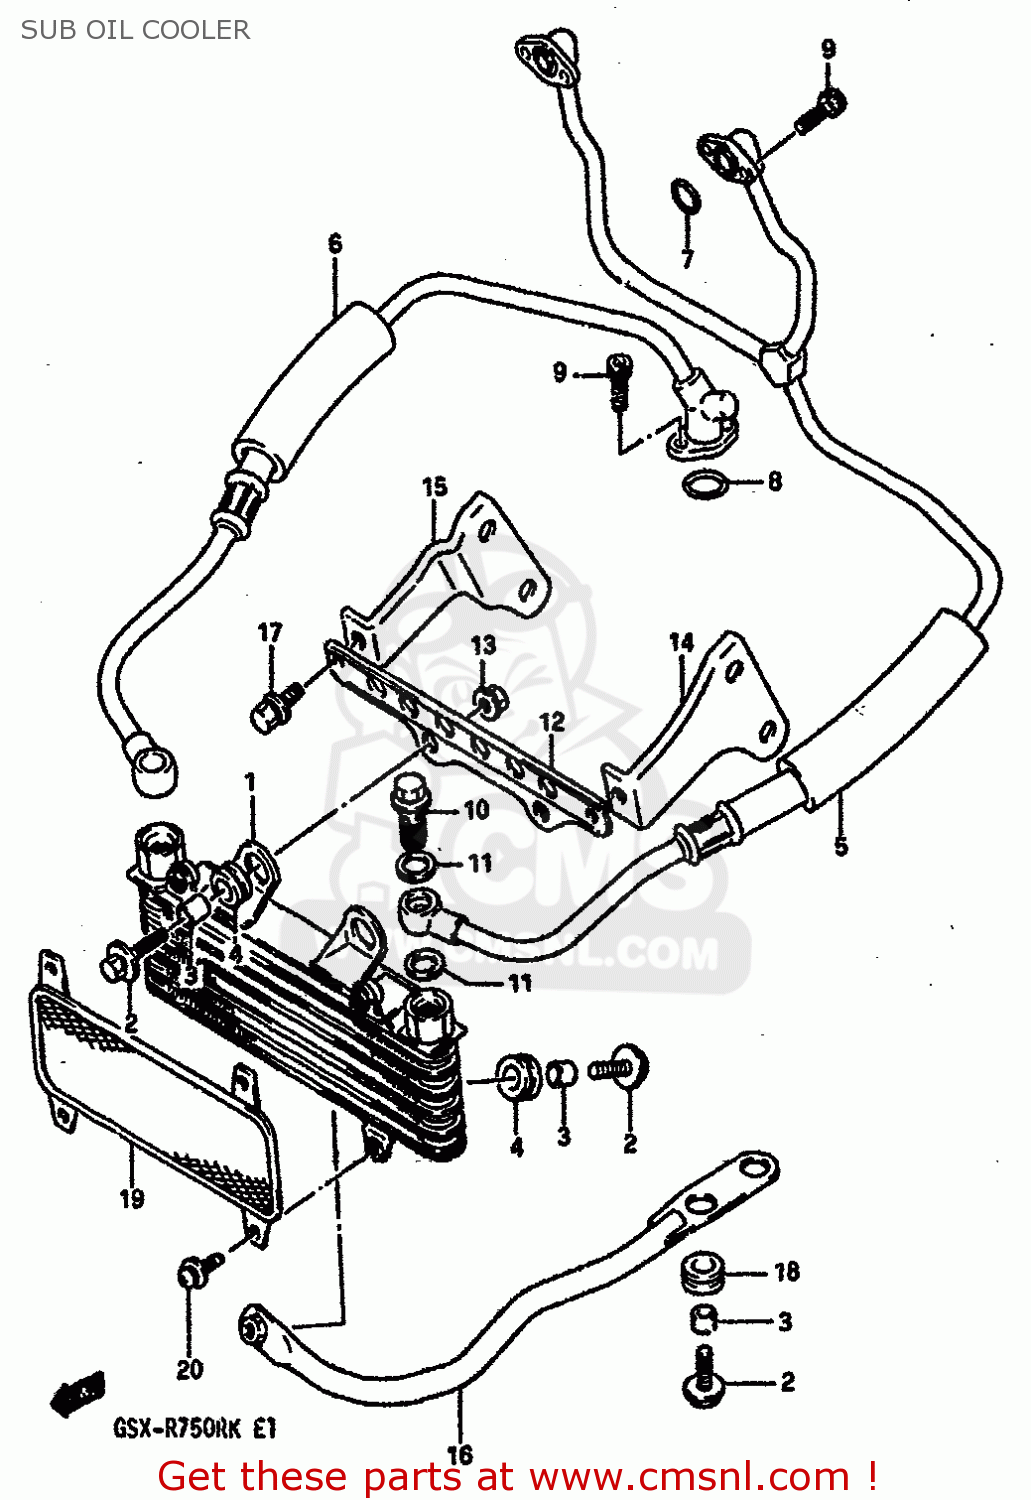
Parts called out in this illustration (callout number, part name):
1	COOLER ASSY,OIL SUB
2	BOLT(6X25)
3	SPACER (6.8X10X10)
4	CUSHION
5	HOSE,SUB COOLER,LH
6	HOSE,SUB COOLER,RH
7	O RING(D:2.5,ID:13.8)
8	O RING(D:2.4,ID:15.8)
9	BOLT
10	BOLT UNION
11	GASKET(12.1X19X1.5) (NAS)
12	BRACKET,OIL COOLER,UPPER
13	NUT
14	BRACKET,OIL COOLER,LH
15	BRACKET,OIL COOLER,RH
16	BRACKET,OIL COOLER,LOWER
17	BOLT
18	CUSHION
19	BUMPER,SUB OIL COOLER
20	SCREW
